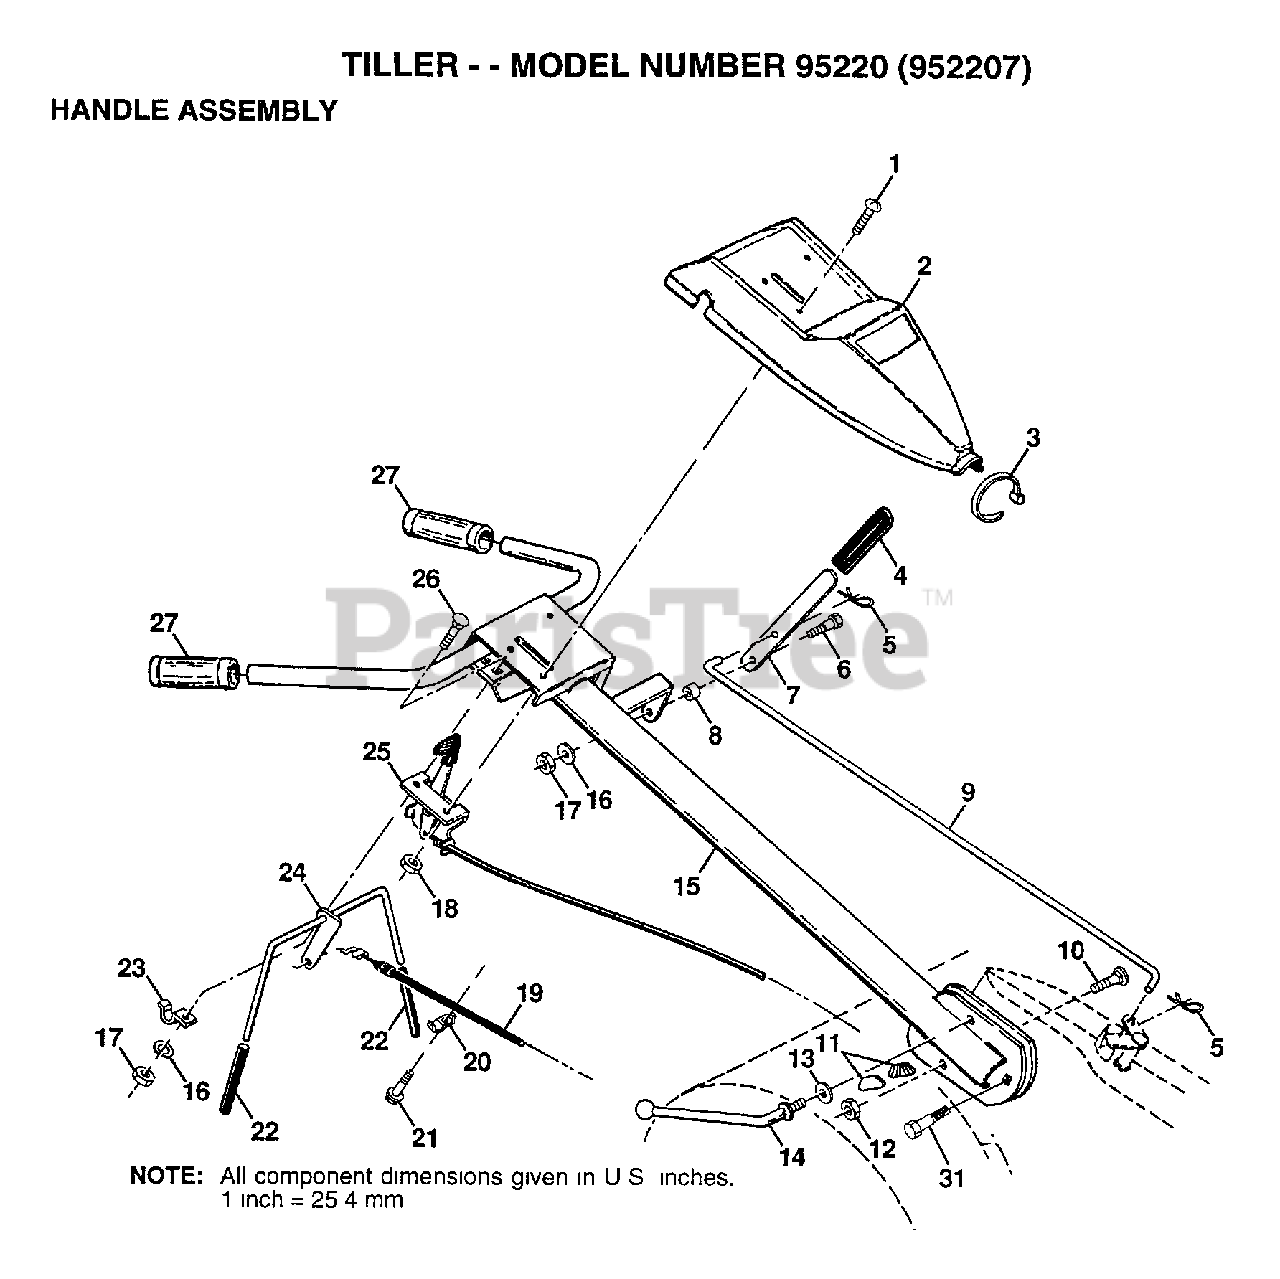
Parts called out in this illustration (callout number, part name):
1	Screw, Pan HD. #10-24
2	"PANEL,CONT TI"
3	TIE CABLE CRT
4	GRIP T
5	RETAINER M
6	SHOULDER BOLT ST
7	SHIFT HANDLE CRT
8	GROMMET CRT
9	SHIFT ROD CRT
10	BOLT D
11	LOCK CRT
12	LOCKNUT
13	WASHER CRT
14	LEVER LOCK CRT
16	LOCKWASHER
19	CABLE.CLUTCH.48.Z
20	CONDIUT CLIP T
22	GRIP BAR CRT
24	"ASSY CONTROL, BAR"
25	"CONT,THROTTLE"
26	BOLT
31	BOLT PIVOT
